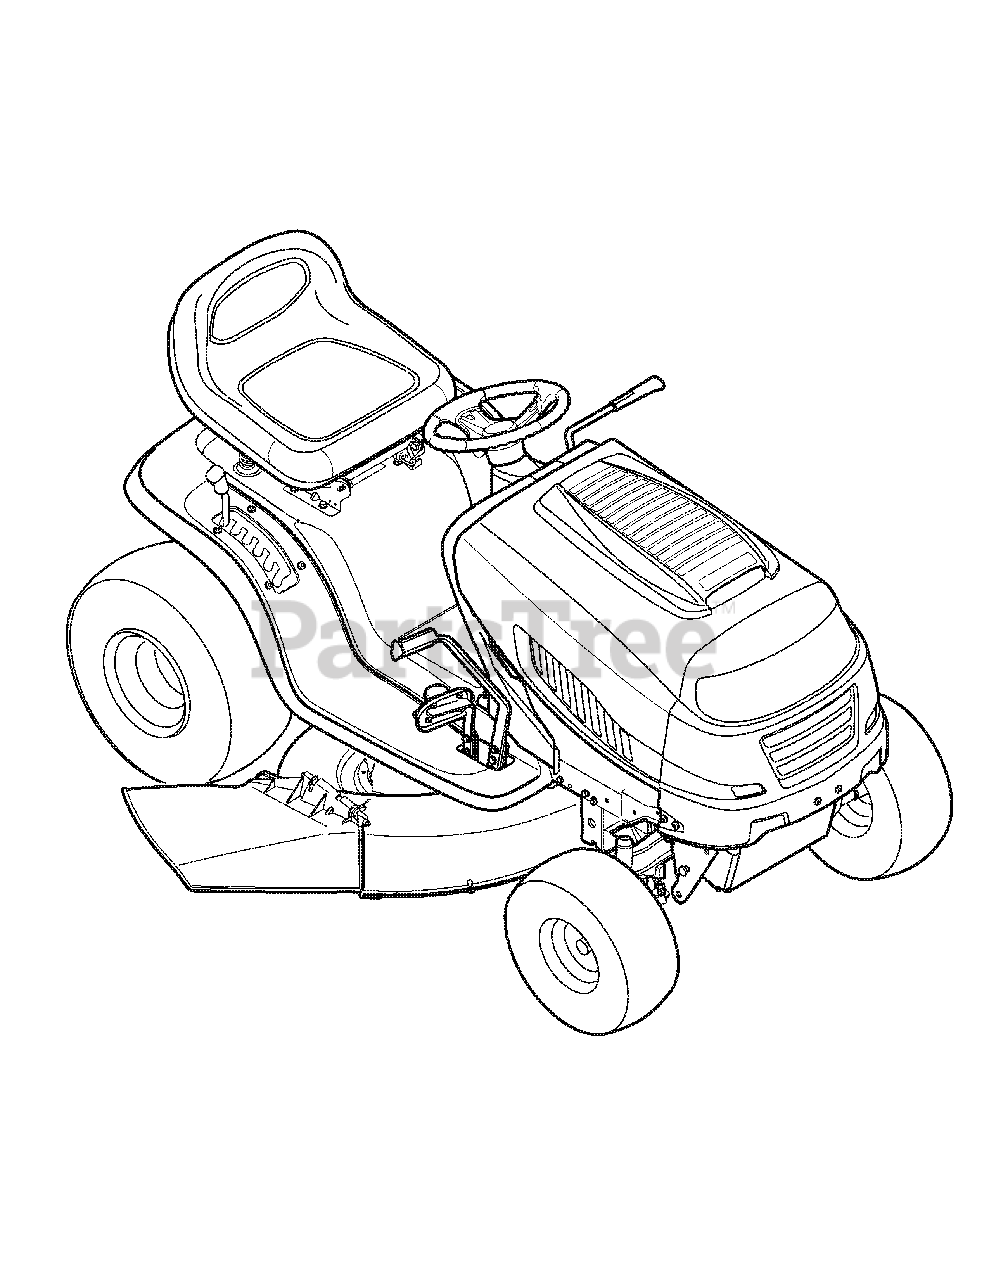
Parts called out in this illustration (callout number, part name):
NA	PRE-CLEANER ELEMENT
NA	UPPER DRIVE BELT
NA	ENGINE TO DECK BELT
NA	WATER NOZZLE ADAPTER
